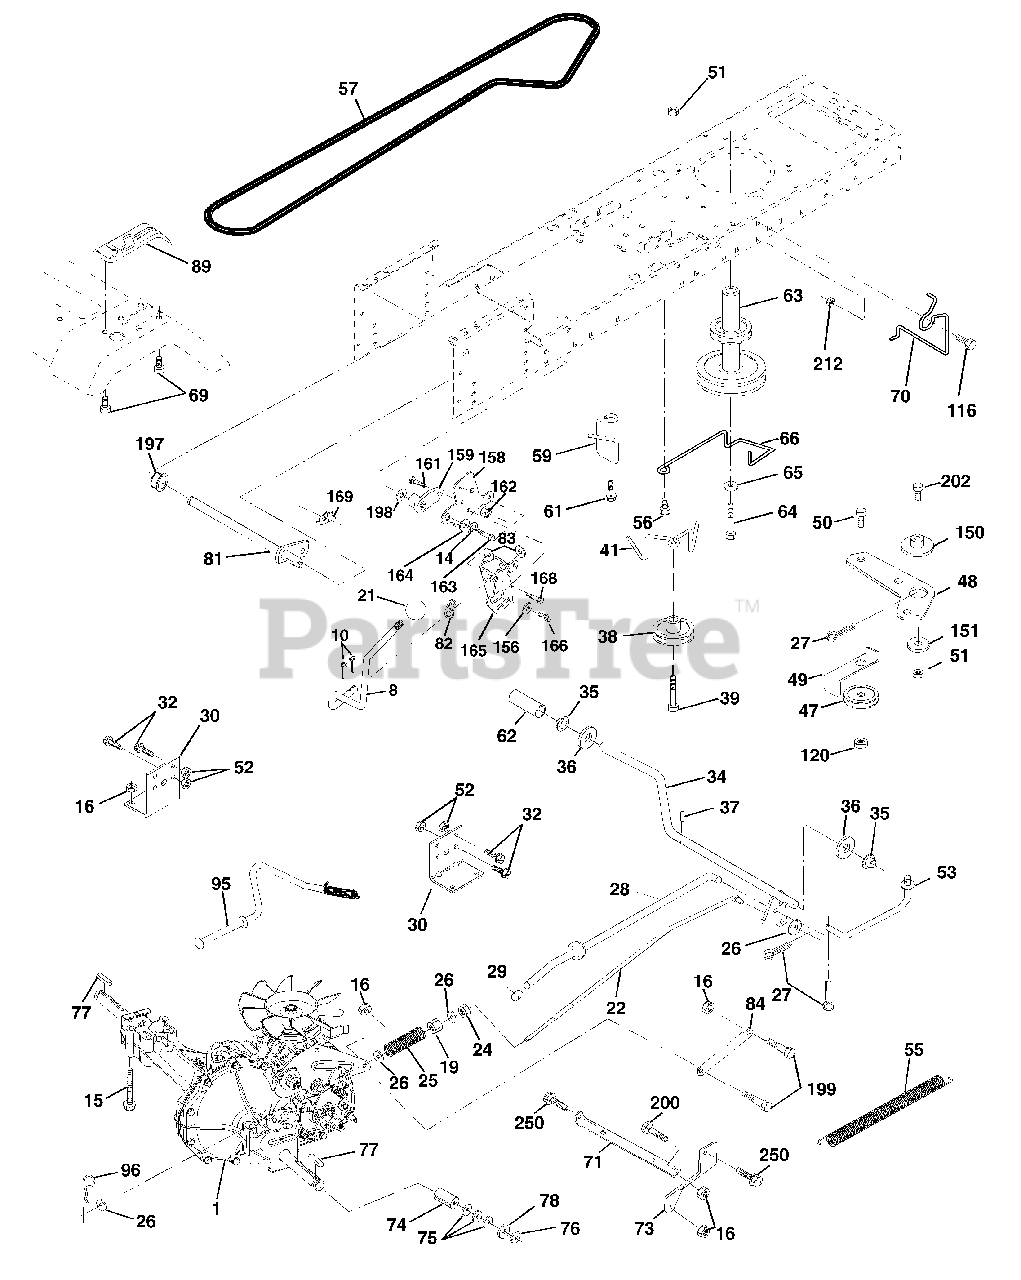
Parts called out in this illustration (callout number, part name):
8	Rod Shift Hydro LT
10	Pin Cotter 1/8 x 1 CAD
14	Washer Lock Hvy Helical
15	Bolt, Hex FLGHD 5/16-18 Gr. 5
16	Nut Lock Hex W/Ins 5/16-18 Unc P
19	Nut Lock Hex W/Wsh 3/8-16 Unc
21	Knob, Round 1/2-13
22	Rod, Brake Hydro
24	Nut
25	Spring, Brake Rod
26	Washer
27	Pin Cotter 1/8 x 3/4 CAD.
28	Rod, Parking Brake
29	Cap, Parking Brake
30	Bracket, Transaxle
32	Bolt Hex Hd 5/16-18 Unc x 3/4
34	Shaft, Foot Pedal
35	Bearing, Nylon
36	Washer
37	Pin, Roll
38	Pulley, Flat Composite
39	Bolt Fin Hex 3/8-16 x 3
41	Keeper, Belt Idler
47	Pulley, Idler, V-Groove
48	Bellcrank Clutch Grnd Drv STL
49	Retainer, Belt
50	Bolt
51	Nut Crownlock 3/8-16 UNC
52	Nut Crownlock 5/16-18 UNC
53	Link, Clutch
55	Spring, Return, Clutch
56	Screw 3/8-16 x 1-1/4
57	V-Belt, Ground Drive
59	Keeper, Center Span
61	Screw 3/8-16 x .875
62	Cover, Pedal
63	Pulley, Engine
64	Bolt, Hex
65	Washer
66	Keeper Belt Engine
69	Screw
70	Guide Belt
71	Strap Torque Lh Hydro
73	Strap Torque Rh Hydro
74	Spacer, Axle
75	Washer 25/32 x 1-1/4 x 16 Gauge
76	E-Ring
77	Key, Square
78	Washer 25/32 x 1-5/8 x 16 Gauge
81	Shaft Asm. Cross Hydro
82	Spring Torsion T/A
83	Washer 17/32 x 3/4 x 16 Ga.
84	Link Transaxle
89	Console, Hydro
95	Control Asm Bypass Hydro
96	Retainer Spring 1" Zinc/Cad
116	Bolt Rdhd Sq Neck 3/8-16 x 1
120	Nut Lock Flg 3/8-16
150	Spacer Retainer
151	Washer 13/32 x 2 x 10 Ga.
156	Washer Srrted 5/16 ID x 1.125
158	Bracket Shift Mount
159	Hub Tapered Flange Shift Lt
161	Bolt Rdhd Sqnk 1/4-20 x 3/4 Gr 5
162	Nut Crownlock 1/4-20 Unc
163	Bolt Hex Fin 1/4-20 Unc x 1 Gr 5
164	Washer 5/8 x .281 x 10 Ga
165	Bracket Pivot Lever
166	Screw 5/16-18 x 5/8
168	Bolt Shoulder 5/16-18 x .561
169	Plate Fastening Lt
197	Nyliner Snap-In 5/8" ID
198	Washer Nyl 7/8 ID x .105
199	Bolt Shoulder 5/16-18 Unc
200	Bolt Rdhd Sqnk 5/16-18 Unc x 1
202	Bolt RDHD 3/8-16 x 1-3/4 Gr 5
212	Nut Hex Flg Lock
250	Screw Thdrol. 3/8-16 x .75
